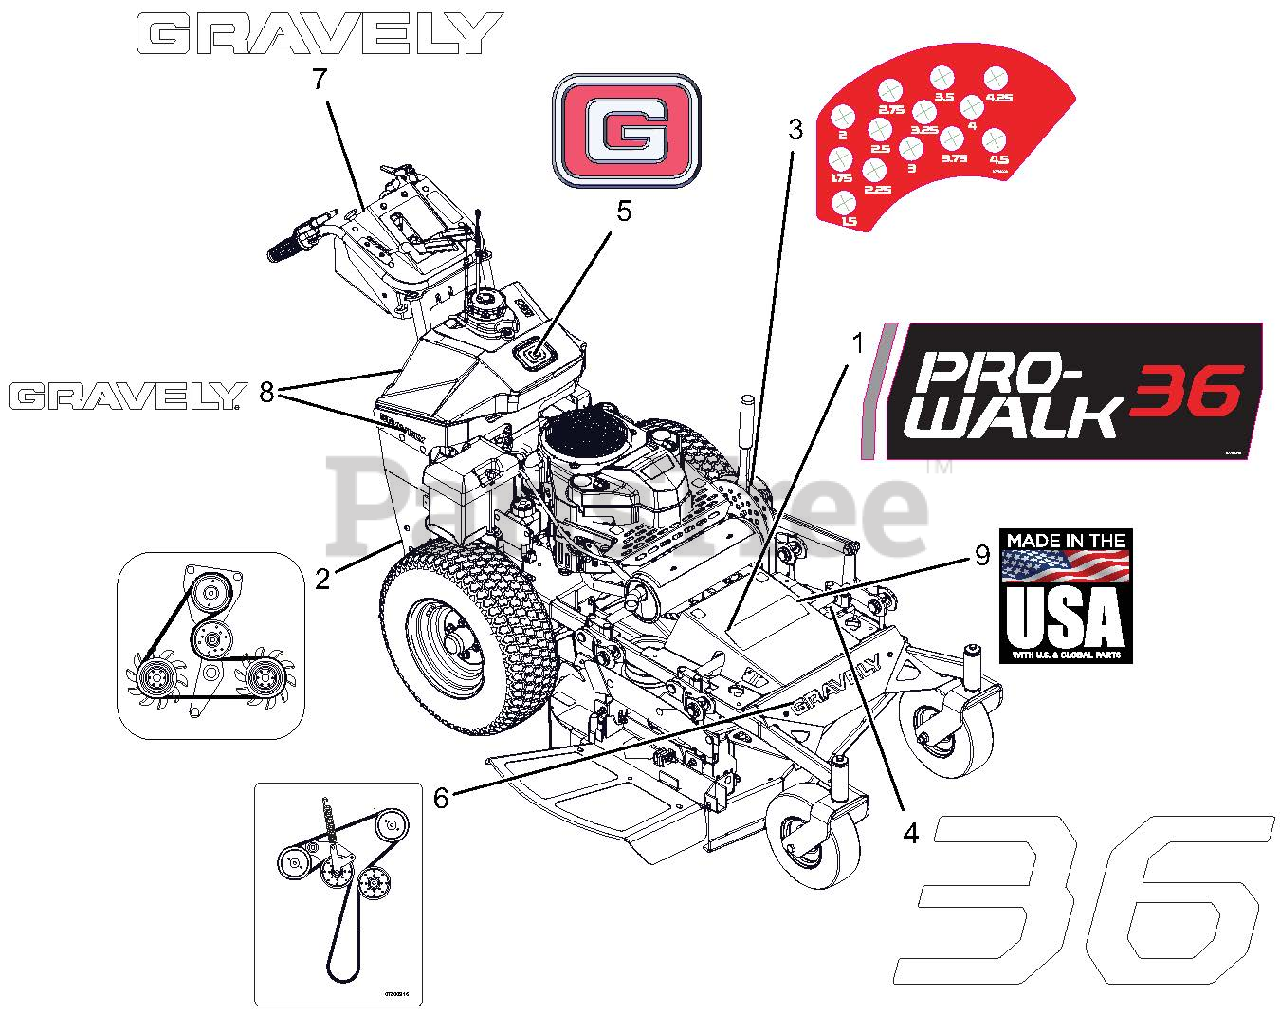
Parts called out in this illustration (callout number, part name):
1	DECAL, PRO WALK 36"
2	DECAL, 36 PW TRANS BELT ROUTE
3	DECAL, 36" HOC
4	DECAL, 36"
5	DECAL, GRAVELY BRAND
6	DECAL, 36 PW DECK BELT ROUTING
7	DECAL, 9.5" GRAVELY LOGO
8	DECAL, 6.5" GRAVELY LOGO
9	DECAL, MADE IN USA
